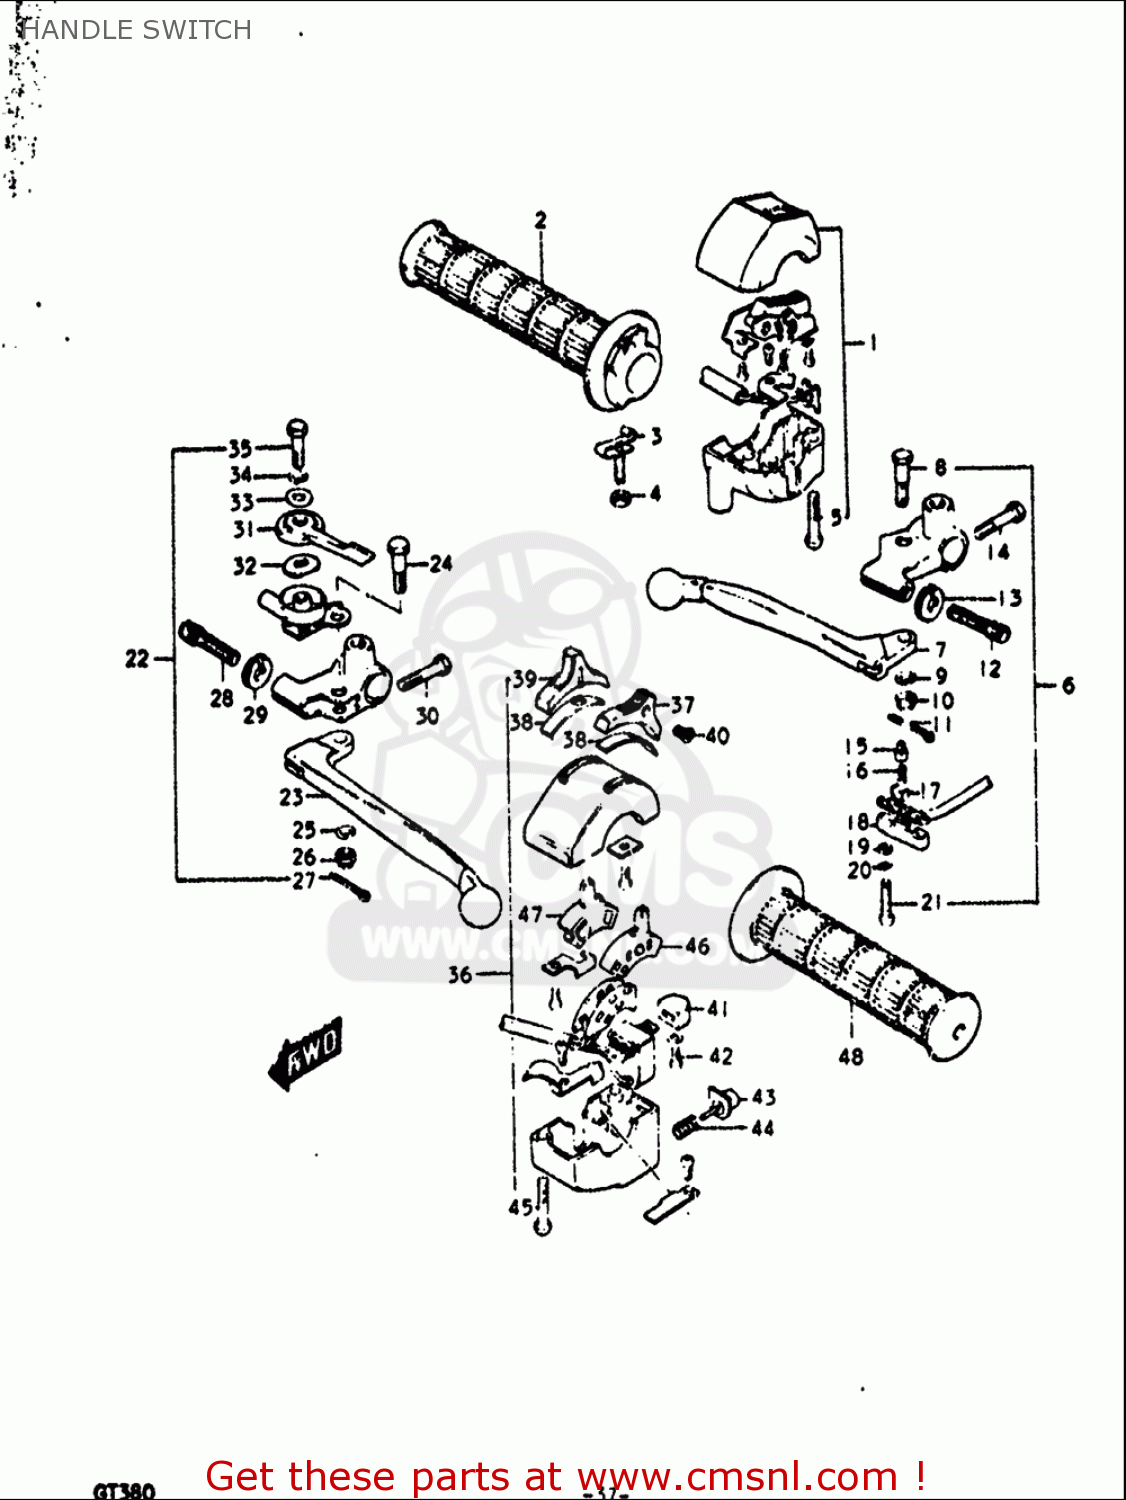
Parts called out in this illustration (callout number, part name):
2	GRIP,THROTTLE
3	ADJUSTER, THROTTLE
4	NUT
5	SCREW
6	BRAKE LEVER & SWITCH ASSY
7	LEVER,BRAKE
8	BOLT,LEVER PIVOT
9	WASHER,LOCK
10	NUT,LEVER FITTNG
11	PIN 16X20
12	ADJUSTER,CABLE
13	NUT,CABLE ADJUSTER
14	BOLT
15	CONTACT,SWITCH
16	CONTACT,SWITCH
17	CONTACT,SWITCH
18	COVER,FR BK TERMINAL BASE
19	WASHER
20	WASHER,LOCK
21	SCREW
23	LEVER,CLUTCH
24	BOLT,LEVER PIVOT
25	WASHER,LOCK
26	NUT,LEVER FITTNG
27	PIN 16X20
28	ADJUSTER,CABLE
29	NUT,CABLE ADJUSTER
30	BOLT
31	LEVER
32	WASHER,ADJUSTER
33	WASHER(6.5X16X1)
34	WASHER,LOCK
35	BOLT
38	PLATE,SWITCH KNOB
39	KNOB
40	SCREW
42	SCREW
43	BUTTON,HORN
44	SPRING,BUTTON
45	SCREW
46	BLOCK, LIGHTING SWITCH
48	GRIP,L
